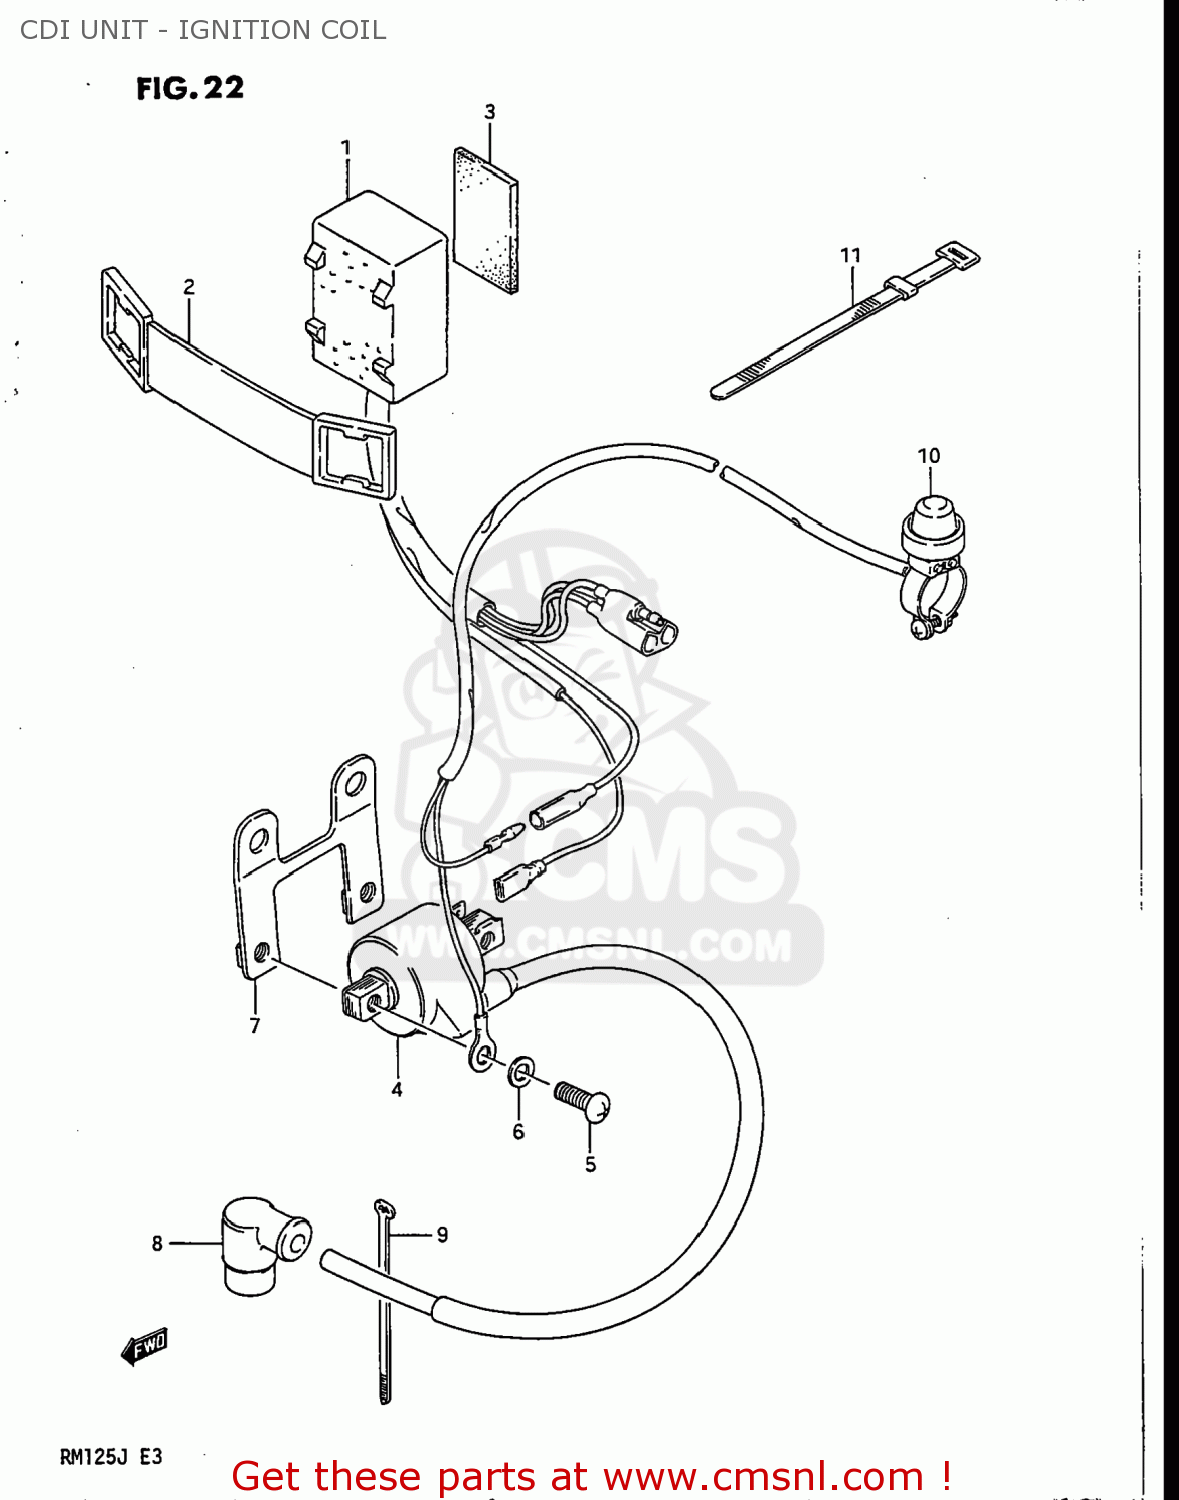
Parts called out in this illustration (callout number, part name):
1	CDI UNIT
2	BAND
3	PROTECTOR(170X95X3.0)
4	COIL ASSEMBLY,IGNITION
5	SCREW
6	WASHER,LOCK
7	BRACKET,IGNITION COIL
8	CAP,SPARK PLUG
9	CLAMP
10	SWITCH ASSEMBLY
11	CLAMP(L:120)
